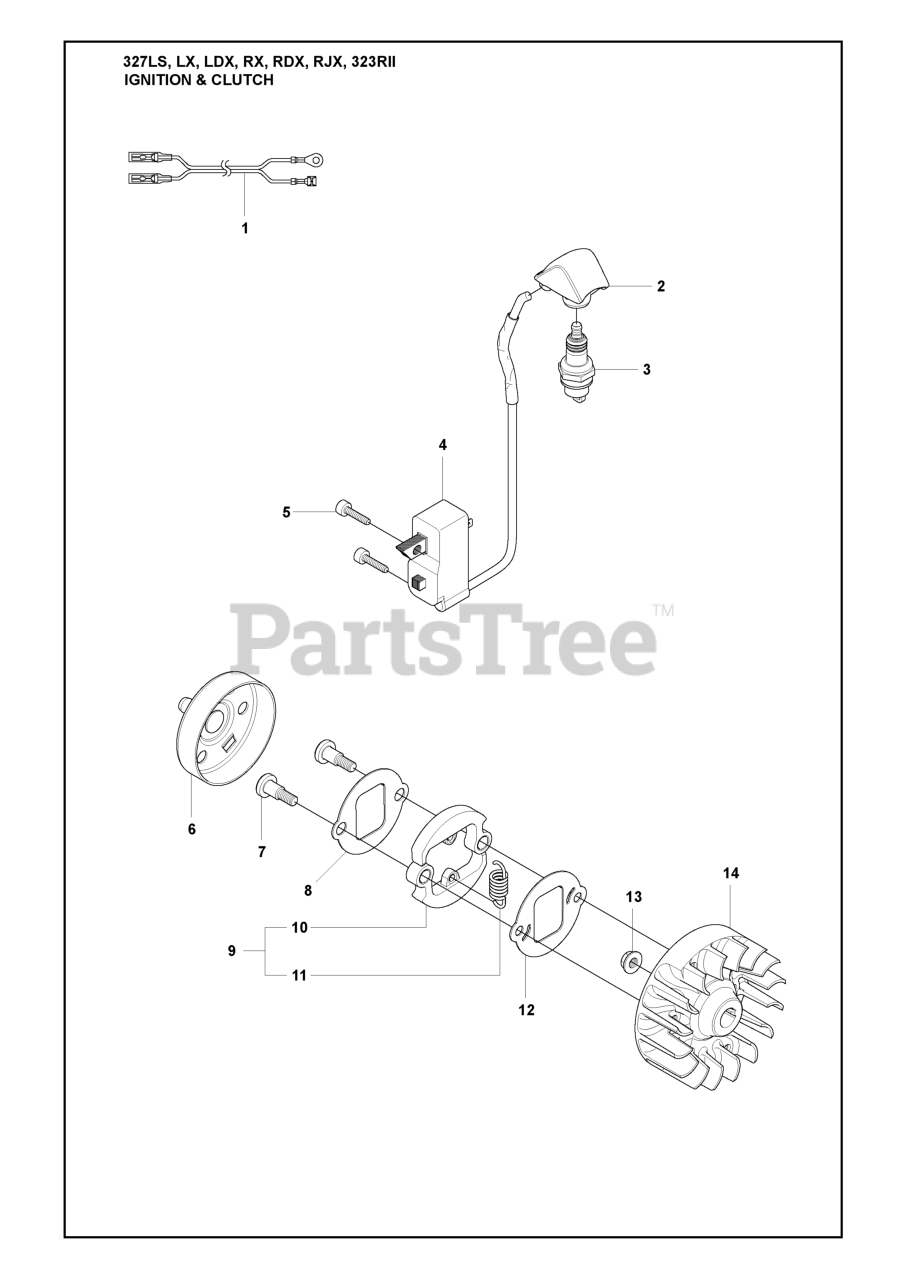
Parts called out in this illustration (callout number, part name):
1	SHORT CIRCUIT CABLE
2	SPARK PLUG CAP
3	Spark Plug, RCJ6Y
4	IGNITION MODULE OPS
6	CLUTCH DRUM
8	WASHER, CLUTCH
13	FLANGE NUT
